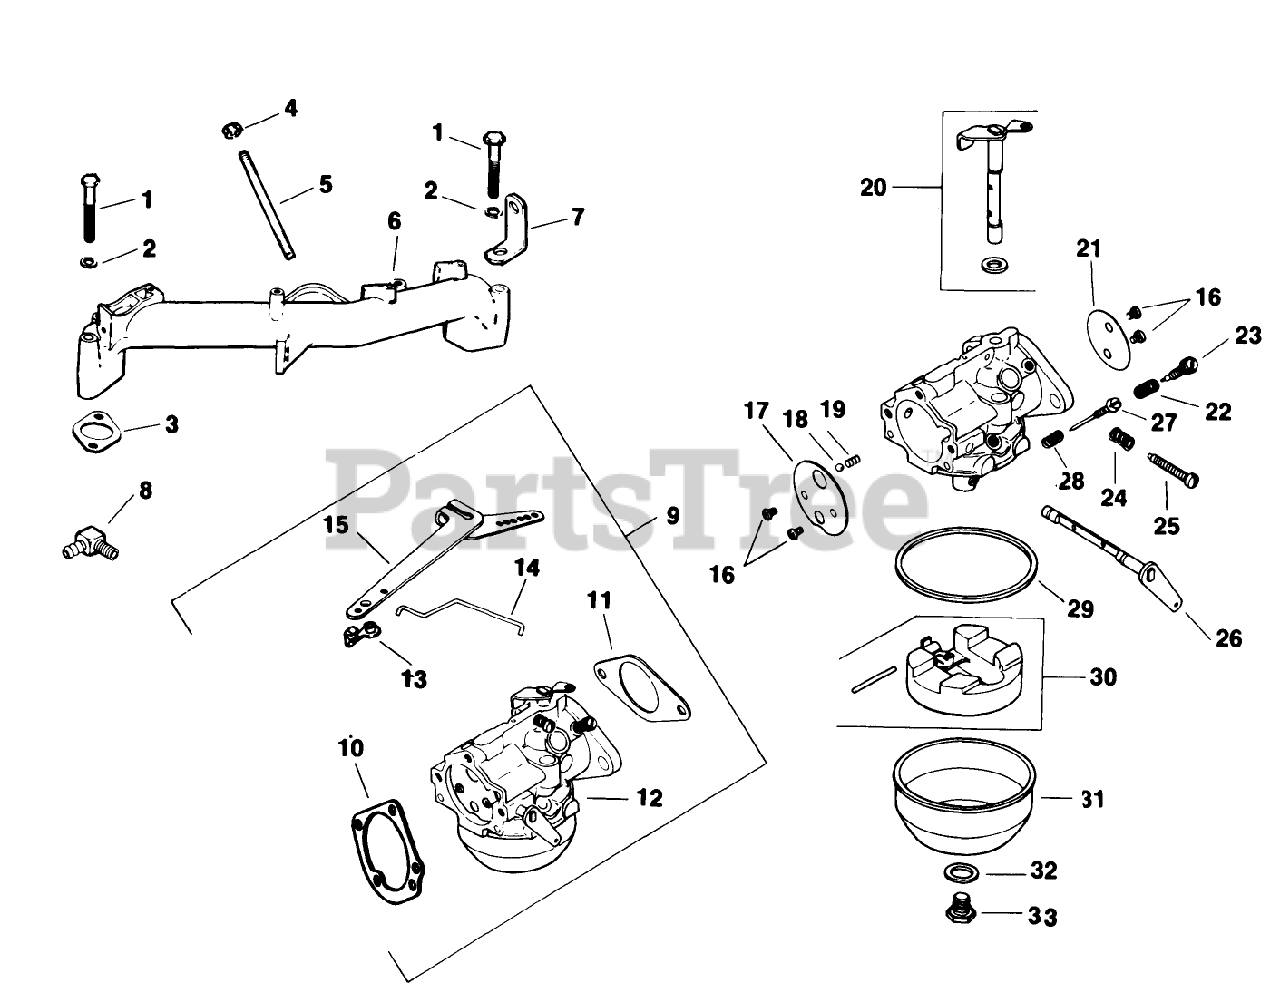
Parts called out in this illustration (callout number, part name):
1	Screw-H.C.
2	Washer
3	Gasket-Intake
4	Nut
5	Stud
6	Manifold-Intake
7	Strap-Lifting
8	Connector-90deg.
9	Kit-Carburetor w/Gasket (Incl. Ref. #10-33)
10	Gasket
11	Gasket
12	Carburetor
13	Bushing
14	Kit-Governor Linkage (Incl. Ref. #13)
15	Arm-Governor
16	Screw-Throttle Plate
17	Plate-Choke
18	Ball-Choke
19	Spring-Choke
20	Shaft-Throttle Lever & Sea
21	Plate-Throttle
23	Valve-Needle
26	Lever-Choke
27	Needle-Main Fuel
29	Bowl-Gasket
30	Kit-Float
32	Gasket-Bowl
33	Screw-Bowl
